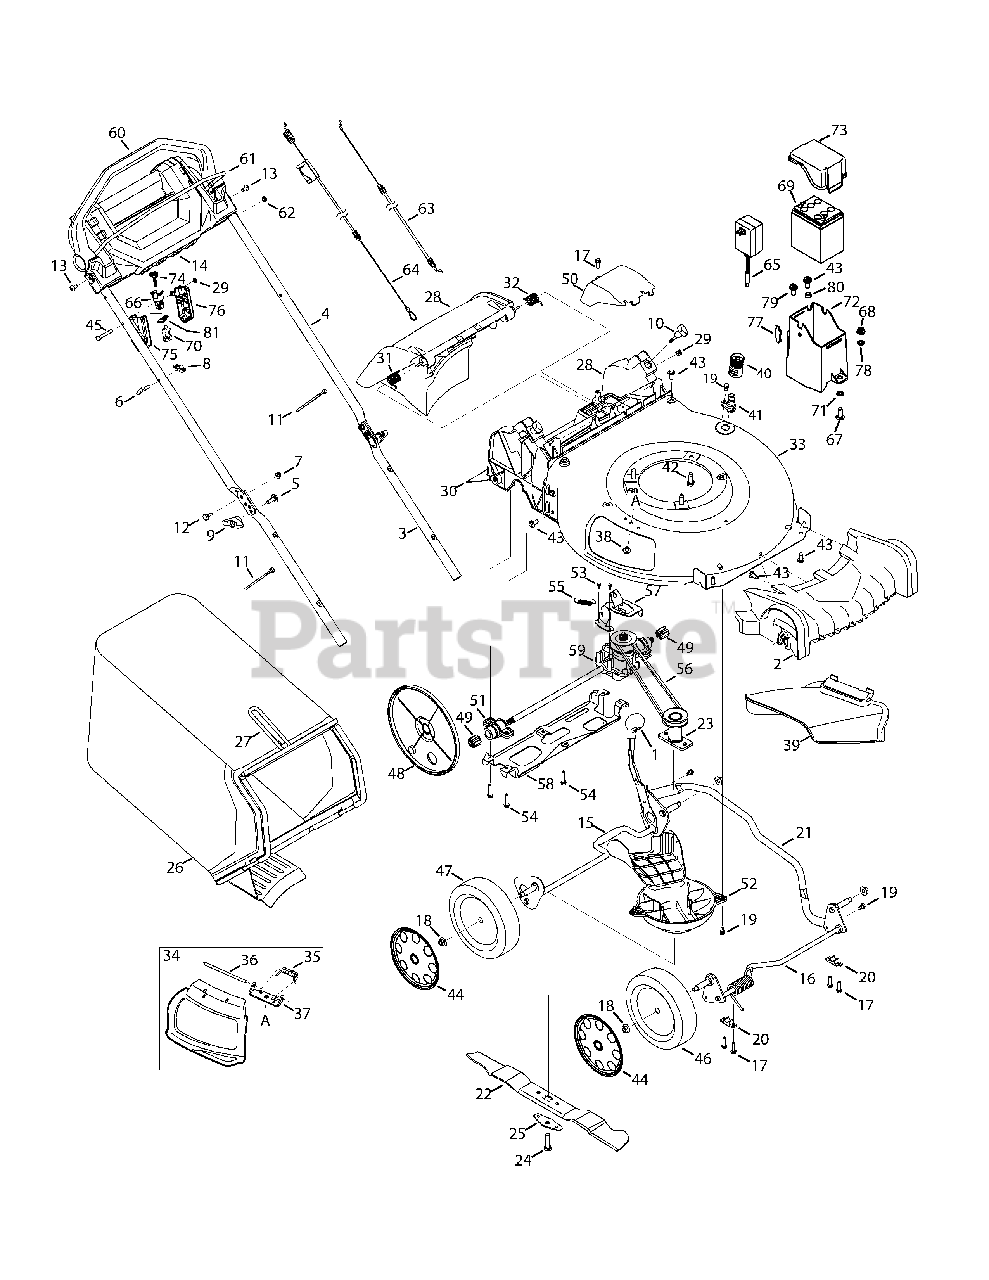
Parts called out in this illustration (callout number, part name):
1	Adjustment Lever Knob
2	Front Cover
3	Lower Handle
4	Upper Handle
5	Carriage Screw, 5/16-18
6	Rope Guide
7	Nut, Flange Lock, 1/4-20
10	Wing Nut
11	Cable Tie
12	Sldr. Screw, .375 x .126 x 1/4-20
13	Screw, 1/4-14 x .625
14	Handle Console
15	Rear Axle Assembly
16	Front Axle Assembly
17	Screw, 1/4-15 x .750
18	Flange Lock Nut, 3/8-16
19	Scr., Shldr., 1/4-20 x .50
20	Bushing, Lock, .505 Dia. X .62
22	Mulching Blade
23	Blade Adapter
24	Screw, 3/8-24 x 1.50
25	Blade Bell Support
27	Grass Catcher Frame
28	Rear Discharge Door Assembly
29	Nut, Sq., 1/4-20
30	Trailing Shield
31	Torsion Spring - RH
32	Torsion Spring - LH
33	Deck , 21"
34	Mulch Plug (Incl. 35-37)
35	Torsion Spring
37	Chute Deflector Bracket
38	Screw, 1/4-20 x .500
39	Side Discharge Chute
40	Water Nozzle Adapter
41	Water Nozzle
42	Screw, 3/8-16 x 1.00
43	Screw, 5/16-14 x .750
44	Hubcap, 8"
45	Screw, 1/4-20 x 1.75
46	Front Wheel
47	Rear Wheel
48	Wheel Dust Cover
49	Spur Gear, 10T
50	Transmission Cover
51	Bearing Assembly
52	Engine Baffle
53	Screw, Hex Washer, .159 x .43
54	Screw, 1/4-15 x 1.25
55	Exten. Spring, 2.405
57	Transmission Bracket
58	Rear Support Bracket
59	Transmission Assembly
60	Drive Handle
61	Blade Control
62	Shoulder Spacer, .18 x .315 x .09
63	Control Cable
64	Drive Cable
65	Battery Charger
66	Key Switch
67	Bolt, Carr., 5/16-18 x 1.00
68	Nut, Flglk., 5/16-18
69	Battery
70	Plunger Switch
71	Speed Nut
72	Battery Housing
73	Battery Housing Top
75	Electric Start Housing, RH
76	Electric Start Housing, LH
77	Lid Seal
78	Washer, Bell, .340 x .872 x .080
79	Screw, Sldr., 5/16-14 x .972
80	Spacer, .340 x .460 x .246
81	Retainer Bracket
